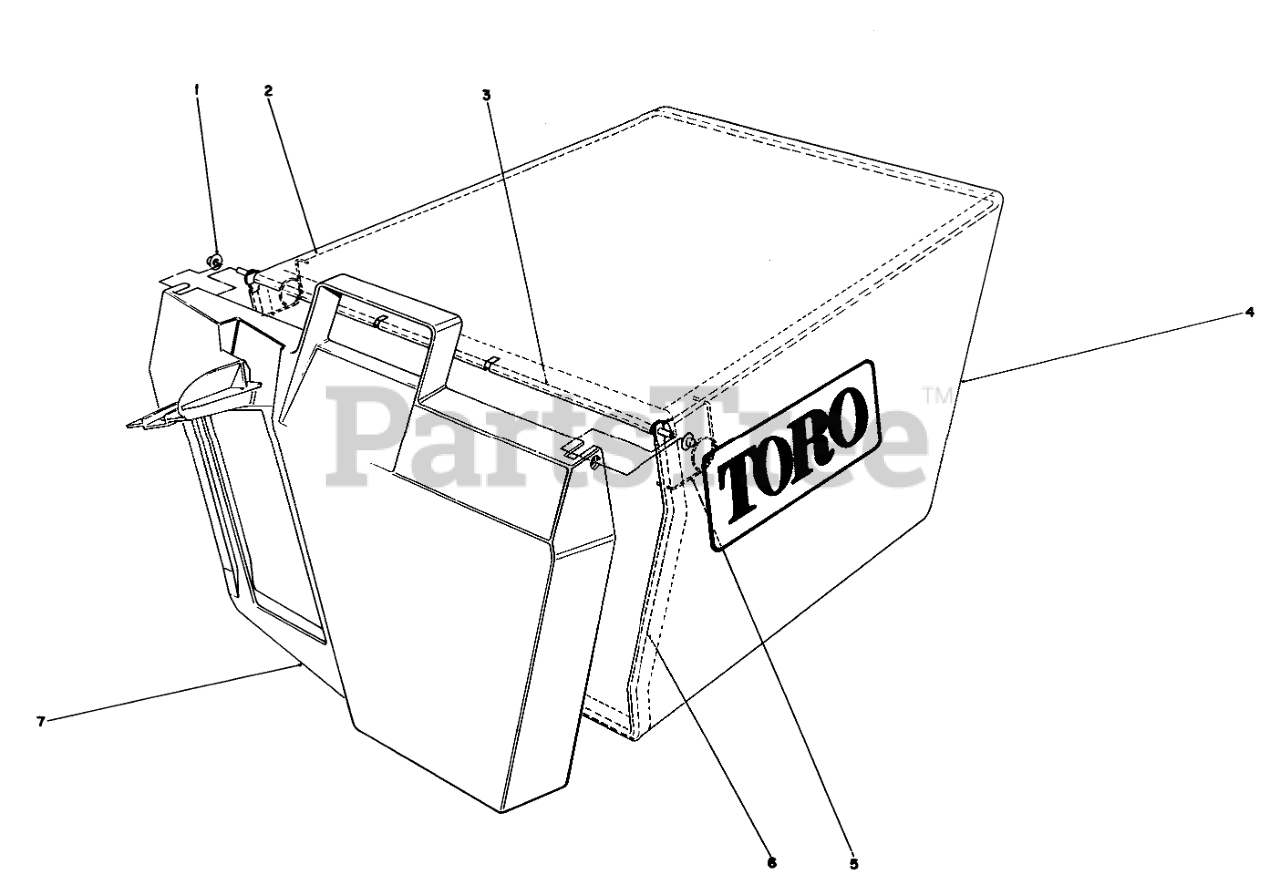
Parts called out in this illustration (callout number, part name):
1	NUT-PUSH
2	FRAME-BAG, UPPER
3	HINGE-DOOR, BAG
4	BAG-GRASS
5	SPRING
6	FRAME-BAG
7	DOOR-BAG
